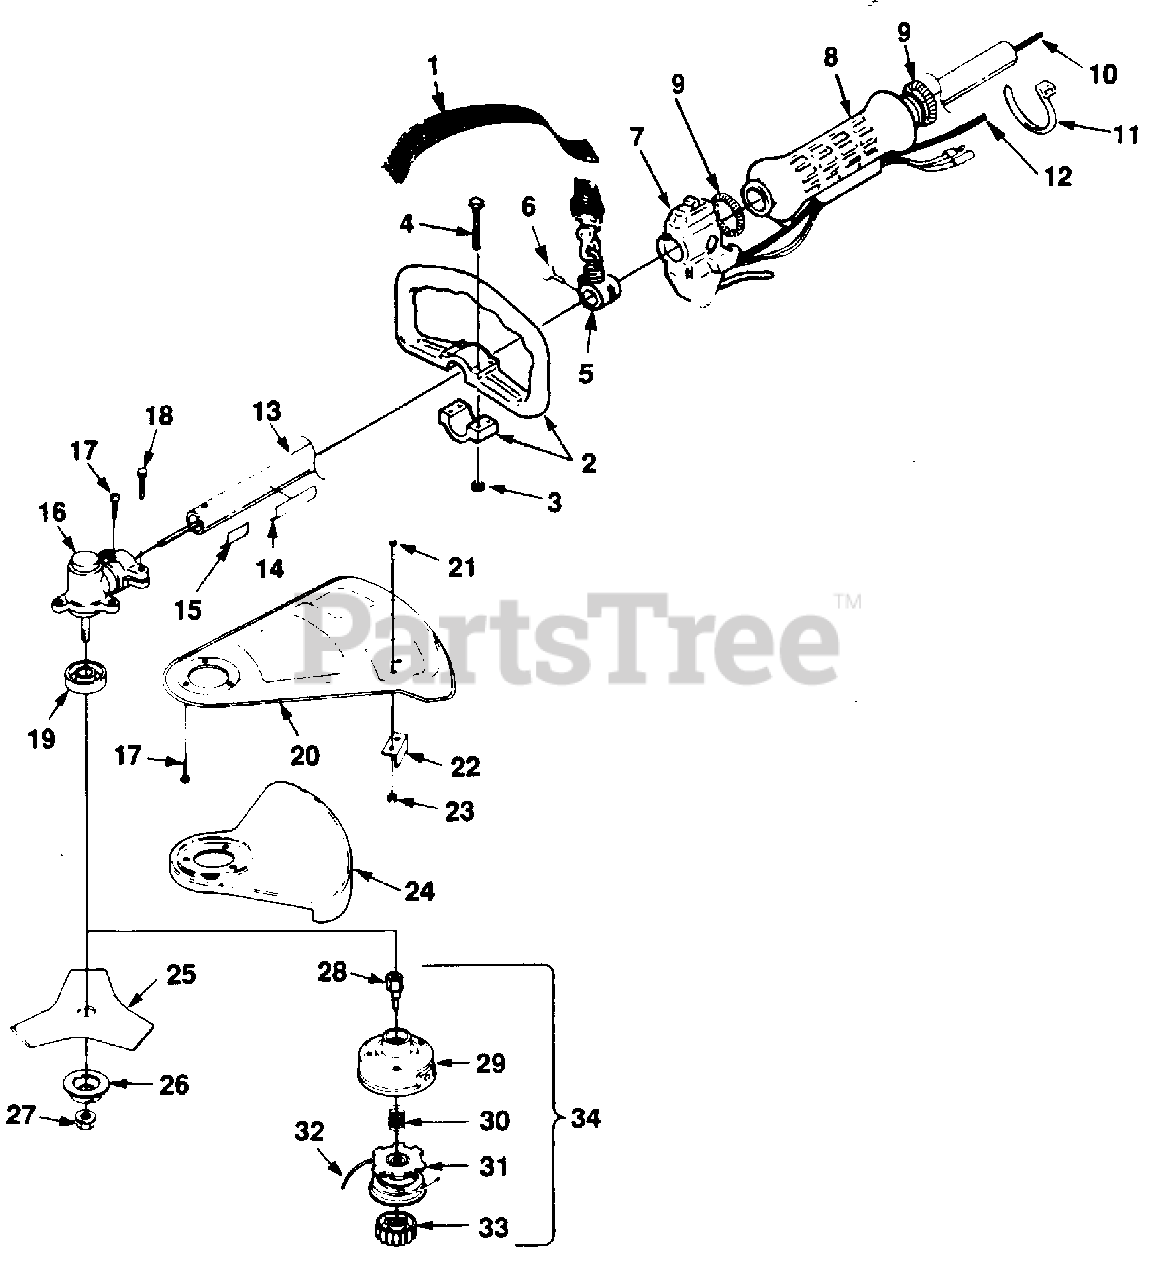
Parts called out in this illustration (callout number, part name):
1	HARNESS w/Connector
2	HANDLE-Front
3	NUT-Hex (M5 X 0.8)
4	SCREW-Hex Hd. (M5 X 0.8 X 35)
5	BRACKET-Hanger
6	SCREW-Thumb (10-24 X 1/2")
7	THROTTLE & SWITCH w/Lead
8	GRIP-Handle
9	SPRING-Tension (HBC-30)
10	SHAFT-Drive
11	CABLE-Tie
12	CABLE-Throttle
13	HOUSING-Drive Shaft (Black)
14	DECAL-Starting Instructions
15	DECAL-Warning
16	GEAR HEAD
17	SCREW-Sems Hex Hd. (10-24 X 1/2")
18	SCREW-Sems Hex Hd. (10-24 X 1")
19	WASHER-Flange
20	DEFLECTOR-Grass
21	SCREW Mach Hex Hd. (10-24 X 3/8")
22	BLADE Cut-Off
23	NUT-(10-24)
24	GUARD-Blade
25	BLADE-Tri-Arc
26	WASHER-Flange
27	NUT-Hex (L.H.)
28	CONNECTOR-Drive
29	HOUSING & EYELET (Dual Line)
30	SPRING-Compression
31	SPOOL & STRING (Dual Line)
32	LINE-Replacement (1 lb. Box, 095" Dia.)
33	RETAINER-Spool (L.H.) (Red)
34	STRINGHEAD COMPLETE
